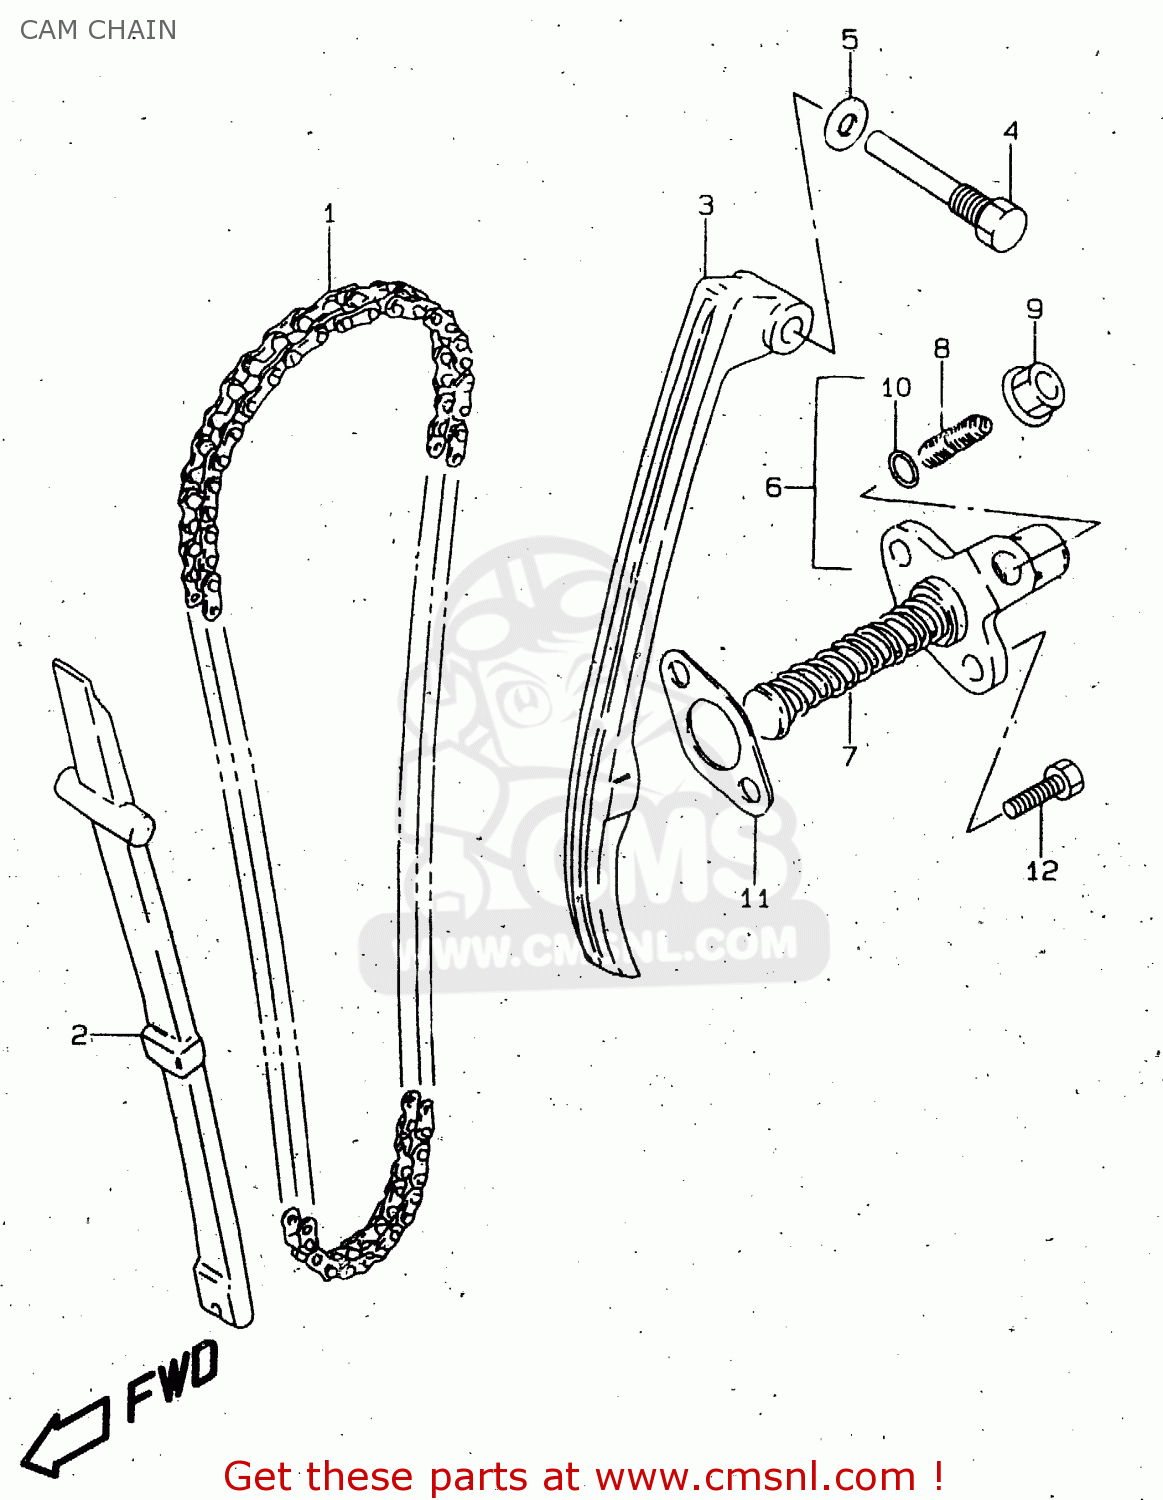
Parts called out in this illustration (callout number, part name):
1	CHAIN,CAMSHAFT DRIVE
2	GUIDE,CAM CHAIN
3	TENSIONER,CAM CHAIN
4	BOLT,CAM CHAIN TENSIONER
5	GASKET 8.2X14X1 (NAS)
6	ADJUSTER ASSY,TENSIONER
7	SPRING
8	SCREW
9	NUT
10	O RING(D:1.9,ID:5.7)
11	GASKET,TENSIONER ADJUSTER (NAS)
12	BOLT
